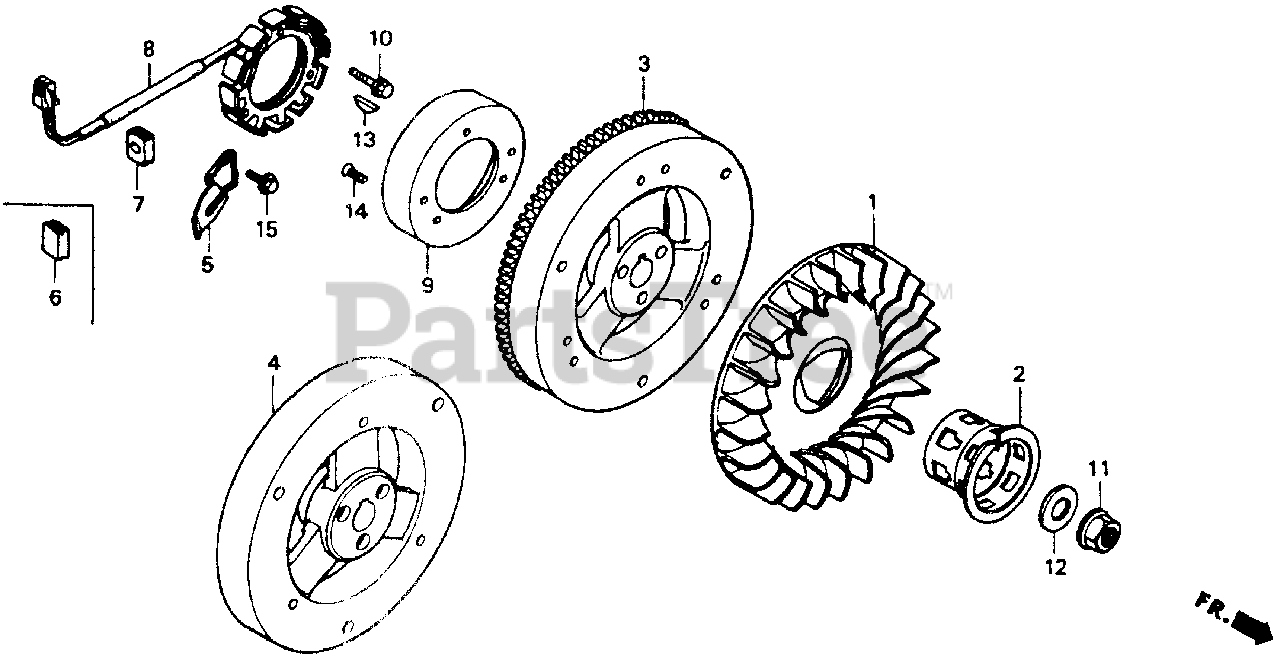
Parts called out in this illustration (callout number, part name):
1	FAN, COOLING
2	PULLEY, STARTER
3	FLYWHEEL (N3-SEL)
5	CLAMP, WIRE
7	GROMMET, WIRE
8	STATOR (1.7A)
9	ROTOR (4MAG)
10	BOLT, FLANGE (6X22)
11	NUT, FLANGE (20MM)
12	WASHER (20MM)
13	KEY, WOODRUFF (50X7)
14	SCREW, FLAT (6X12)
15	BOLT, FLANGE (6X12)
